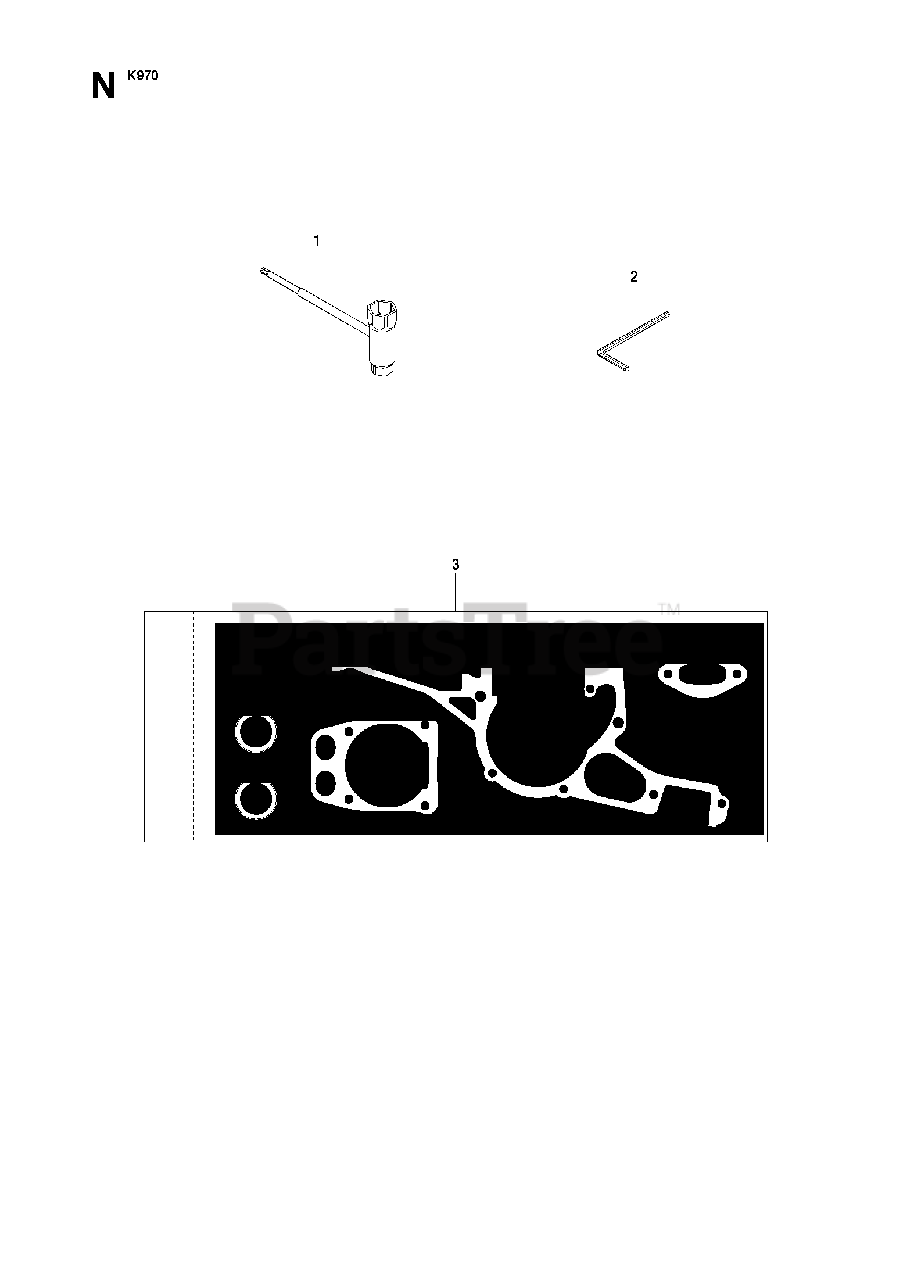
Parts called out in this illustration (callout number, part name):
3	GASKET KIT
4	SEALING RING
7	GASKET
